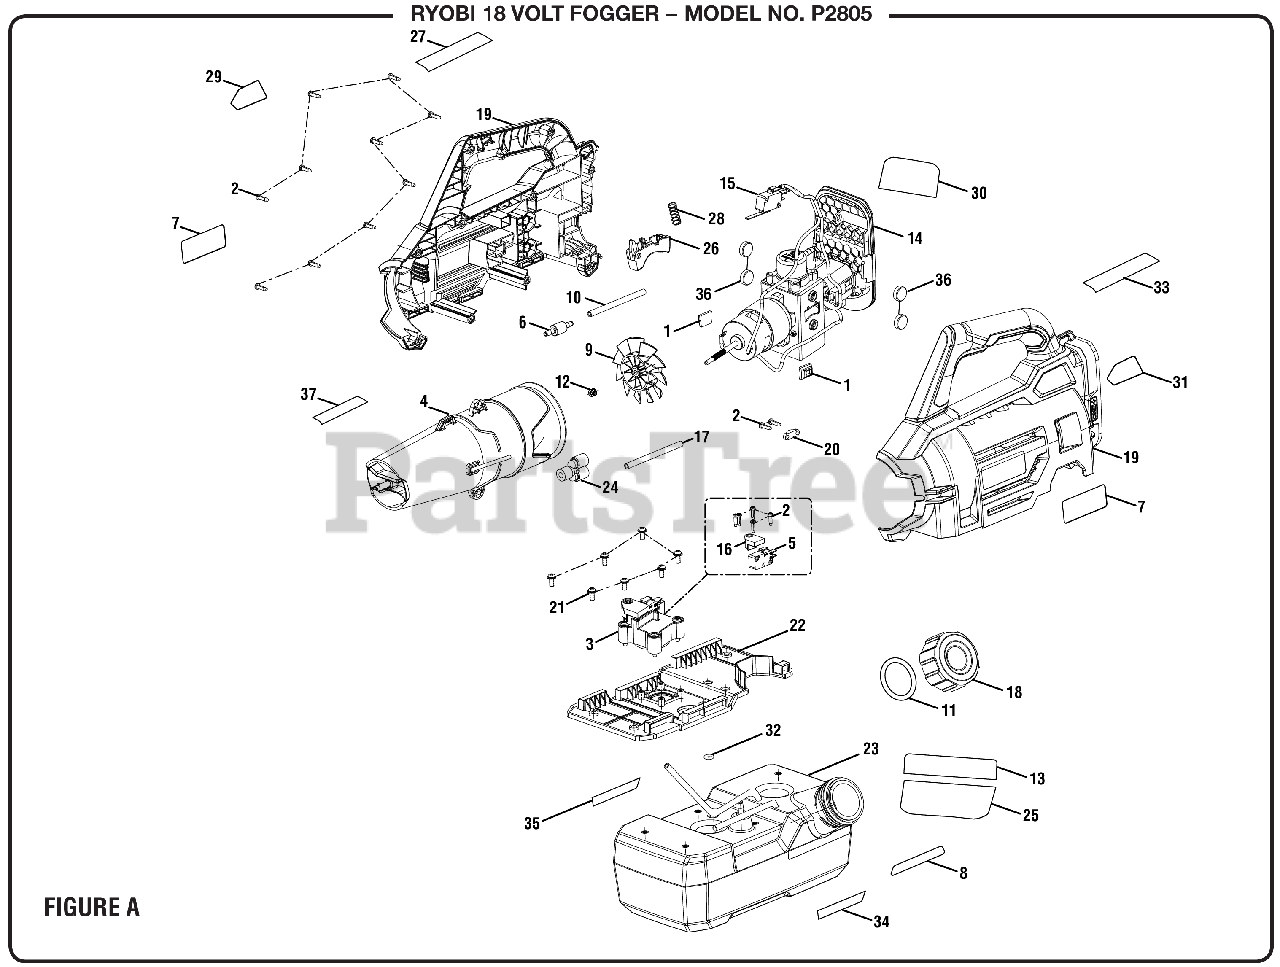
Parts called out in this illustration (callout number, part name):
1	Rubber Plate, EPDM
2	Screw (M4 x 14 mm, T15 Torx Pan Hd.))
3	Pressure Switch Assembly
4	Stator Tube Assembly
5	Pressure Switch
6	Backflow Valve
7	Logo Label
8	Max Fill Label
10	Tube (OD6.35 x ID4.0)
12	Wavy Spring
13	Danger Label
14	Motor, Pump, Switch & Battery Foot Assembly
17	Tube (OD6.35 x ID4.0)
18	Tank Cap Assembly
19	Housing Assembly
20	Strain Relief Plate
21	Screw w/Lock Washer (M5 x 8 mm, Pan Hd.)
22	Tank Plate
23	Tank Assembly
24	Y Connector
25	Warning Label
26	Switch Trigger
27	Icon Warning Label
28	Compression Spring
29	18 Volt Label (Right)
30	Data Label
31	18 Volt Label (Left)
33	Icon Warning Label
34	Do Not Overfill Label (English)
35	Do Not Overfill Label (French/Spanish)
36	Rubber Cap
37	Defender Label
